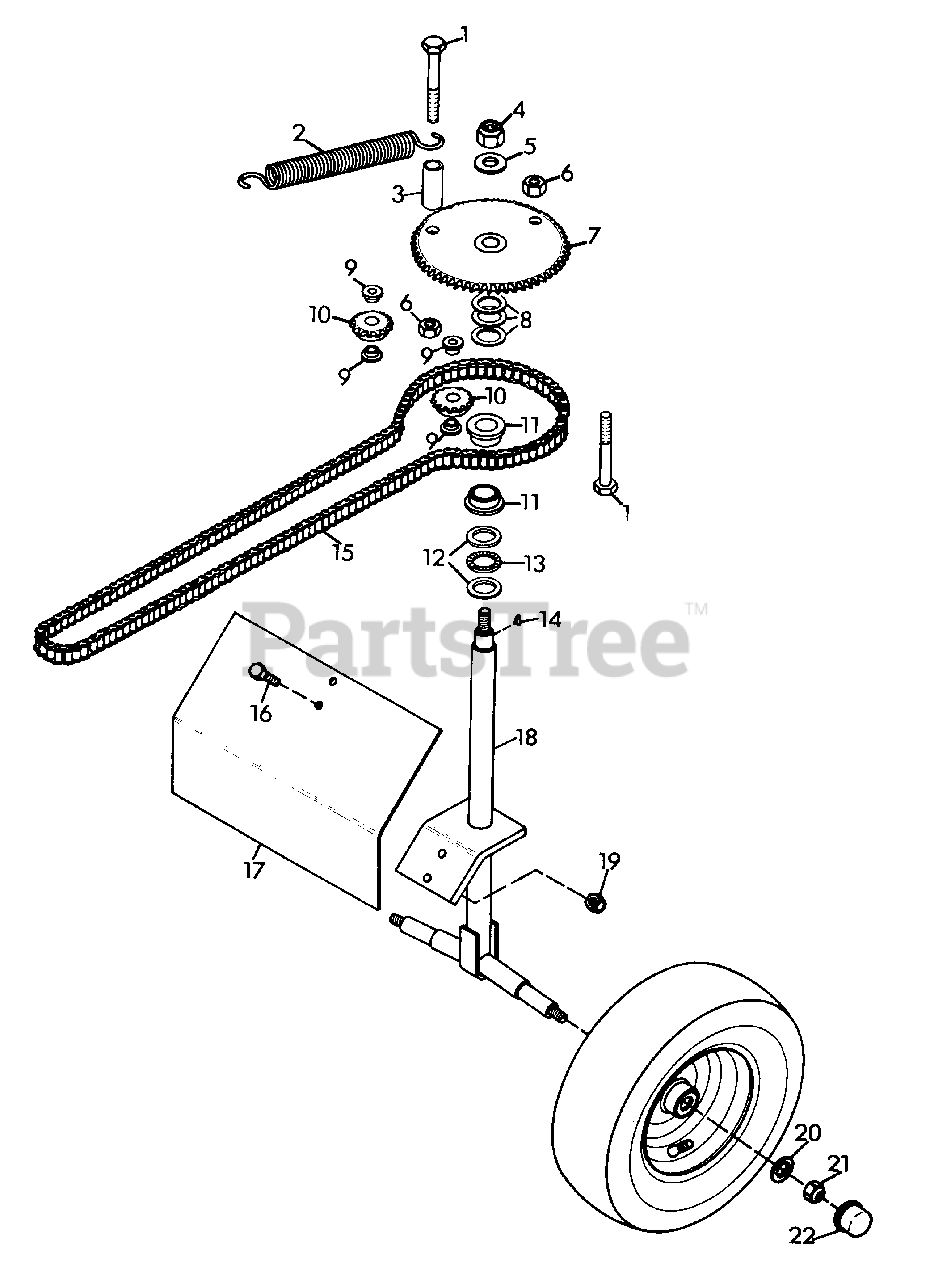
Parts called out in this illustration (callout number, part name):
1	BOLT, HEX 1/2-13X3.25
2	SPRING
3	SPACER, .850X.546X2.18
4	NUT, LOCK 7/8-9
5	WASHER, FLAT .969X2.250X.165
6	NUT, HEX 1/2-13
7	SPROCKET, 60-T #40
8	RACE, THRUST
9	BUSHING
10	SPROCKET, DRIVE
11	BEARING, FLANGED
12	BEARING, THRUST RACE
13	BEARING, NEEDLE THRUST
14	KEY, WOODRUFF .250X.875 HARD #A
15	CHAIN, #40
16	BOLT, HEX 1/2-13X1.25
17	FENDER, PRO MASTER
18	WELDMENT, PRO MASTER AXLE
19	NUT, LOCK 1/2-13
20	WASHER, FLAT .812X1.496X.134
21	NUT, LOCK 3/4-10
22	CAP, DUST
